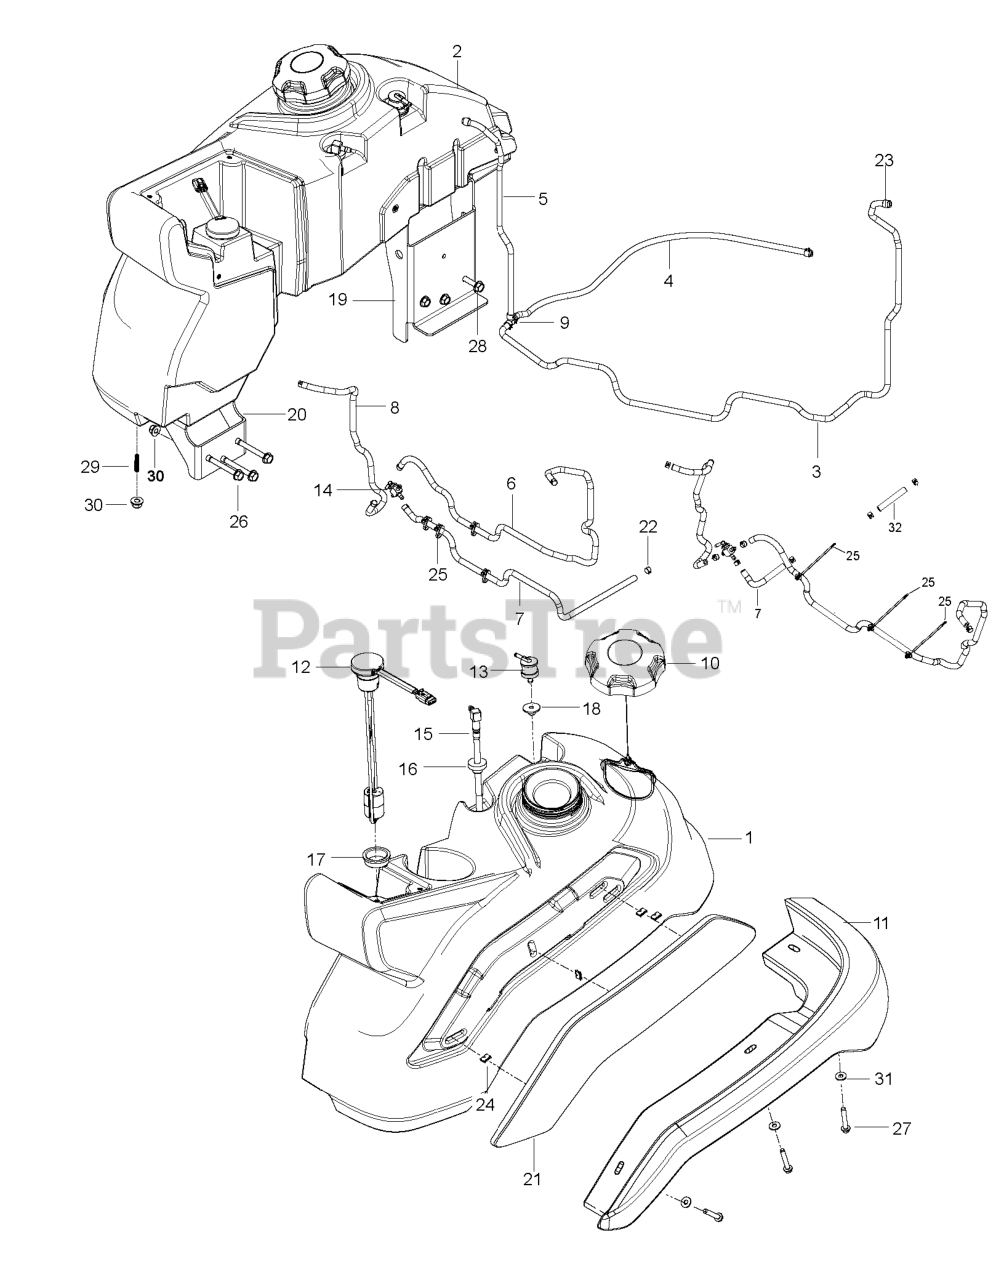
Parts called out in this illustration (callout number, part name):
1	FUEL.TANK.ASM.LH.PZ.REFRESH.18
2	FUEL.TANK.ASM.RH.PZ.REFRESH.18
3	HOSE 3/16" VAPOR LINE 41" LENG
4	HOSE.3/16".VAPOR.LINE.17"LGTH
4	HOSE.3/16".VAPOR.LINE.23"LGTH
5	HOSE.3/16".VAPOR.LINE.17"LGTH
6	HOSE 1/4" LOW PERMEATION FUEL
7	HOSE.1/4".LOW.PERM.FUEL.LN.8"
7	HOSE.1/4".LOW.PERM.FUEL.LN.37"
8	HOSE.1/4".LOW.PERM.FUEL.LN.24"
9	TEE, FUEL LINE 3/16"
10	CAP, FUEL
11	GUARD.MUD.LH
12	SENSOR.FUEL.LVL.FLOAT.V500
13	VALVE.FUEL.CHECK
14	FUEL VALVE
15	TUBE.ASM.FUEL.TANK.PICK-UP.LH
16	BUSHING OUTLET T
17	GROMMET, FUEL SENSOR
18	GROMMET.CHECK.FUEL
19	BRACKET.FUEL.TANK.REAR.SUP.431
20	BRACKET.FUEL.TANK.REAR.SUP.431
21	COVER.LH.FUEL.TANK/CONSOLE APP
22	HOSE CLAMP
23	CLAMP, HOSE
24	CLIP.U-TYPE
25	CABLE.TIE.6".FIRTREE.PZ.REFRES
25	TIE WRAP, 8-3/8", W/CLIP
26	BOLT HEX FLGHD 5/16-18X3 GR. 5
27	SCREW.1/4-20X1.5IN.HEX.MACH
28	SCREW
29	SCREW.5/16-18X1.25"THREADED
30	5/16-18 NYLOC FLANGE NUT
31	WASHER
32	HOSE.1/4".LOW.PERM.FUEL.LN.3"
